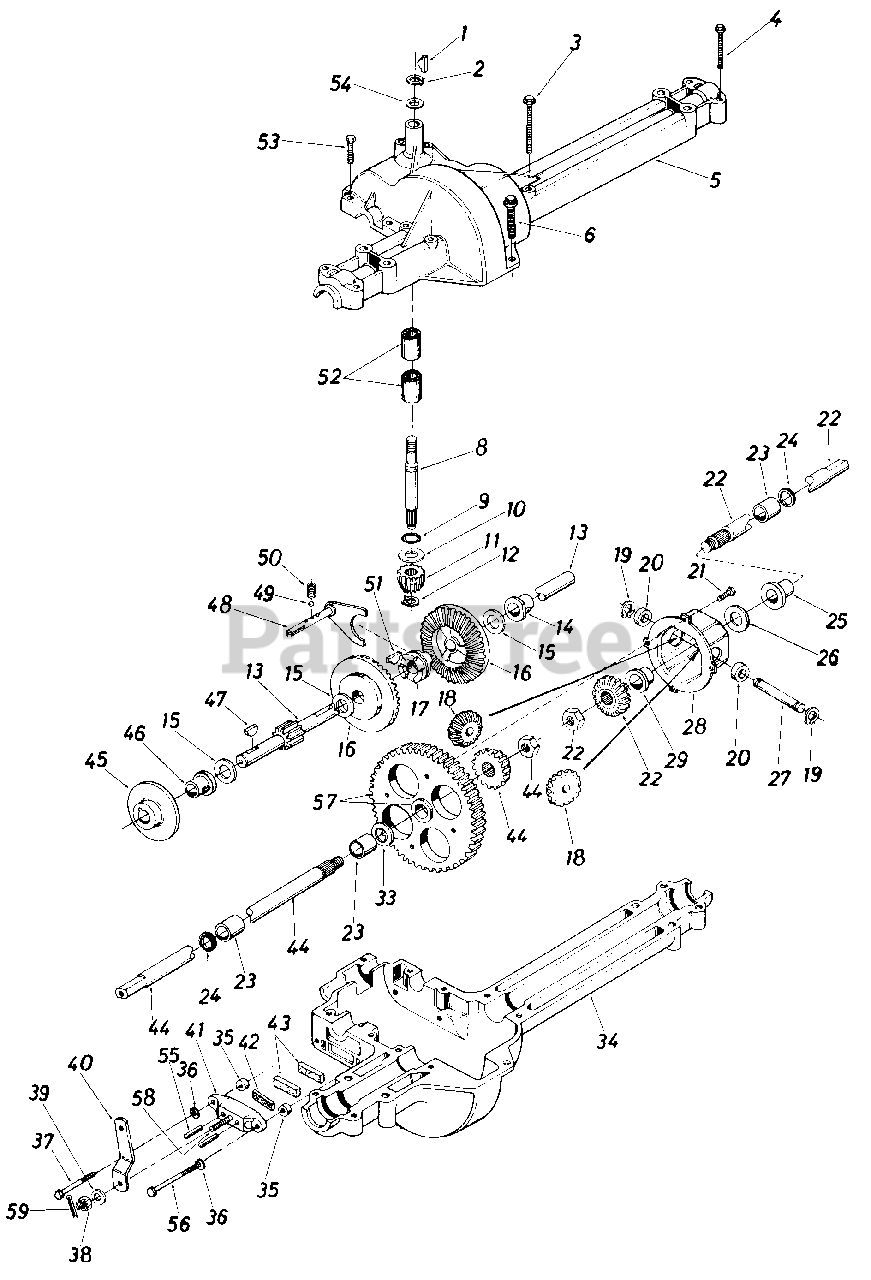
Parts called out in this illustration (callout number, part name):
1	#4 Hi-Pro Key 3/32 x 518" Dia.
2	Snap Ring .625" Shaft
3	Hex Bolt 1/4-20 x 1.75" Lg.
4	Hex Tap Scr. 1/4-20 x 1.25" Lg.
5	Upper Housing
6	Hex TT-Tap Scr. 1/4-20 x .75" Lg.
9	Square Seal 5/8" I.D.
10	Thrust Washer 5/8" I.D. x 1.25" O.D.
11	Pinion Input 14T
12	Retaining Ring 7/16" Ext.
14	Flange Brg. 5/8" I.D. x 3/4" Lg.*
15	Fl-Wash.
16	Bevel Gear 42T
17	Clutch Collar
18	Miter Gear 15T
19	Retainer Ring
20	Thrust Bearing
21	Pan Head Scr. 1/4-20 x .50" Lg. w/Patch
22	Axle R.H. Ass'y.
23	Sleeve Bearing 3/4" I.D. x 1.0" Lg.
24	Oil Seal 3/4" I.D.
25	Flange Bearing 3/4" I.D. x 15/16" Lg.
26	Fl-Wash. .760" I.D. x 1.5" O.D.
28	Differential Housing Ass'y.
33	Fl-Wash. .760" I.D. x 1.5" O.D.
34	Lower Housing
35	Spacer .53" O.D. x 3/8" Lg.
36	L-Wash. 1/4" I.D.*
37	Hex Bolt 1/4-20 x 1.50" Lg. (Grade 5)
38	Castle Nut 5/16-24 Thd.
39	Fl-Wash. .344" I.D. x .875" O.D.
40	Actuating Arm
42	Puck Plate
43	Brake Puck
44	Axle L.H. Ass'y.
46	Flange Bearing 5/8" I.D. x 15/16" Lg.
47	Woodruff Key 3/16 x 5/8 HT
48	Shift Fork Ass'y.
49	Ball Detent .250" Dia.
50	Spring Detent
51	#9 Hi-Pro Key 3/16" x 3/4" Dia. HT
52	Needle Brg. 5/8" I.D. x 1/2" Lg.
53	Hex Bolt 1/4-20 x 1.00" Lg.
54	Fl-Wash. 5/8" I.D. x .030
55	Actuating Pin 5/16" Dia.
56	Hex Bolt 1/4-20 x 2.50" Lg. (Grade 5)
57	Differential Gear 72T Ass'y. w/Bearing
58	Sq. Hd. Bolt 5/16-24 Thd.
59	Cotter Pin 3/32 Dia. x 1.0" Lg.
